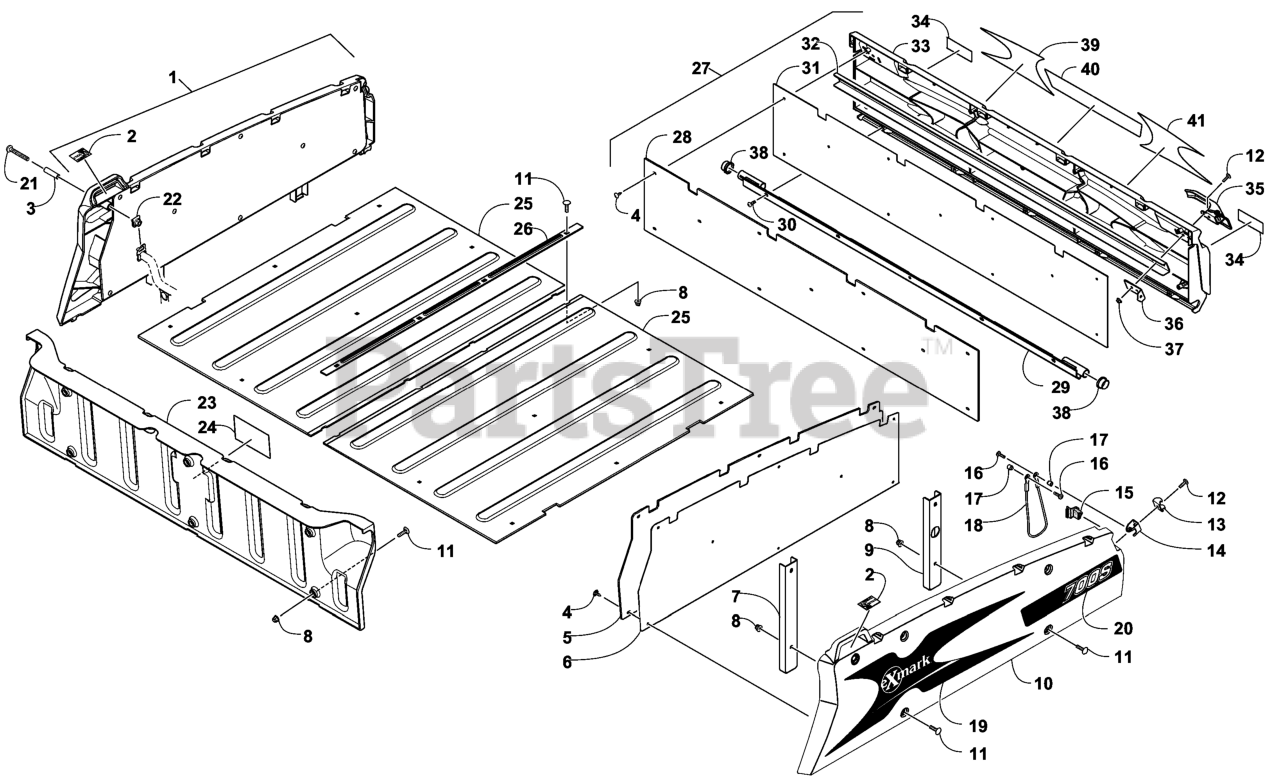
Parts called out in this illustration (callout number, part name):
1	RH SIDE CARGO BOX ASM
1	LH SIDE CARGO BOX ASM
2	DECAL-WARNING, BOX
3	TUBE-SPACER
4	SCREW-TSTRH, SELFTAP
5	PANEL-INNER, CARGO BOX
6	PAD-FOAM, SIDE PANEL
7	BRACKET-SIDE MOUNT, REAR
8	NUT-HHF
9	BRACKET-SIDE MOUNT, FRONT
10	PANEL-SIDE, RH
10	PANEL-SIDE, LH
11	BOLT-CARR
12	SCREW-TSPRH
13	BRACKET-LATCH
14	BRACKET-LATCH
15	PAD-TAILGATE, RH
15	PAD-TAILGATE, LH
16	SCREW-TSPNH
17	SPACER-TAILGATE CABLE
18	CABLE-TAILGATE
19	DECAL-BOX-X LH
20	DECAL-BOX, RH SIDE 700
20	DECAL-BOX, LH SIDE 700
21	SCREW-TSPNH
22	CLIP-SIDE PANEL MOUNTING
23	PANEL-FRONT
24	DECAL-WARNING, CARGO
25	PANEL-BED, CARGO BOX
26	STRIP-BOX BOT CENTER
27	TAILGATE ASM
28	PANEL-INNER, TAILGATE
29	PIVOT-TAILGATE
30	SCREW-TSPH
31	PAD-FOAM, TAILGATE
32	SUPPORT-TAILGATE
33	PANEL-TAILGATE
34	REFLECTOR-REAR
35	LATCH-TAILGATE
36	BRACKET-LATCH, SUPPORT
37	NUT-HHF
38	BUSHING-PIVOT, TAILGATE
39	DECAL-TAILGATE, RH SIDE
40	DECAL-TAILGATE, CENTER
41	DECAL-TAILGATE, LH SIDE
